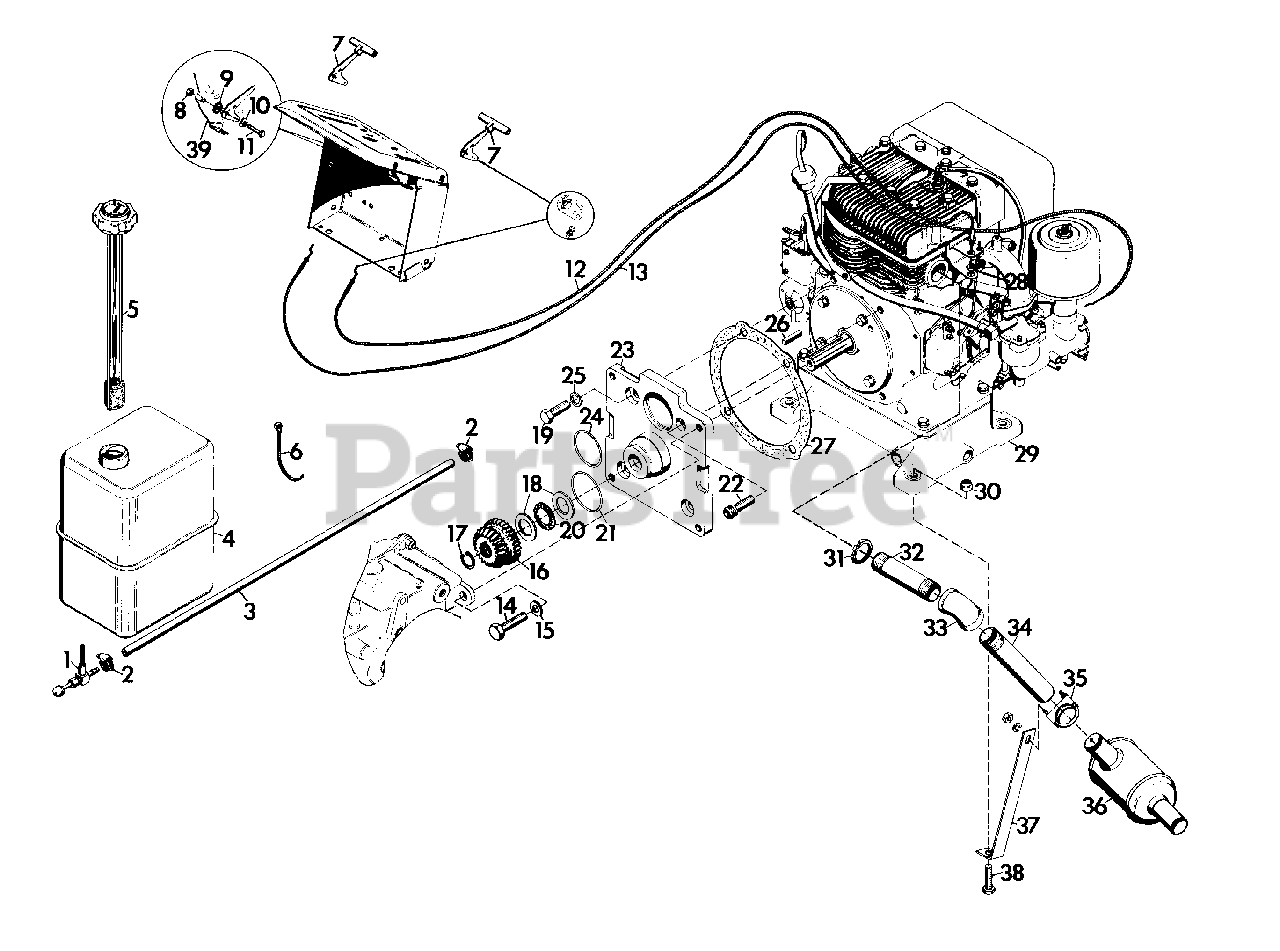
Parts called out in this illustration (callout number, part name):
1	VALVE, FUEL 90 DEG. REVERSE FLOW
2	CLAMP, HOSE
3	LINE, FUEL
4	TANK, FUEL
5	GAUGE, GAS
6	TIE, CABLE
7	ASSEMBLY, KNOB AND LEVER
8	NUT, LOCK 1/4-28
9	WASHER, FRICTION
10	WASHER, SPRING
11	BOLT, HEX 1/4-28X.75
12	ASSEMBLY, CHOKE CONDUIT
13	ASSEMBLY, THROTTLE CONDUIT
14	BOLT, HEX 1/2-13X1.25
15	WASHER, LOCK 1/2 REG.
16	GEAR, SPUR AND BEVEL, INPUT
17	RING, RETAINING 1.125 SHAFT
18	RACE, BEARING THRUST 1.127X1.740X.060
19	BOLT, HEX 7/16-14X1.125
20	BEARING, THRUST 1.127X1.740X.078
21	O-RING, 3.000X3.188X.094
22	SCREW, CAP 7/16-14X1.0 SOCKET HEAD
23	ADAPTOR, ENGINE
24	O-RING, 2.500X2.750X.125
25	WASHER, LOCK 7/16 SP HEAVY
26	KEY, SQUARE .250X1.250
27	GASKET, ADAPTOR
28	NUT, PLASTIC CONDUIT
29	ENGINE, 16 HP B&S
30	NUT, LOCK 3/8-16
31	NUT, CONDUIT 1" PIPE
32	NIPPLE, PIPE 1X6
33	PIPE, 1 IN. ELBOW
34	NIPPLE, PIPE 1"X8.4" SPECIAL
35	CLAMP, MUFFLER
36	MUFFLER, EXHAUST
37	SUPPORT, EXHAUST
38	BOLT, HEX 3/8-16X1.25
39	BRACKET, MOUNTING
NS	NUT, LOCK 10-32
NS	SCREW, MACHINE 10-32X.50 PHD
